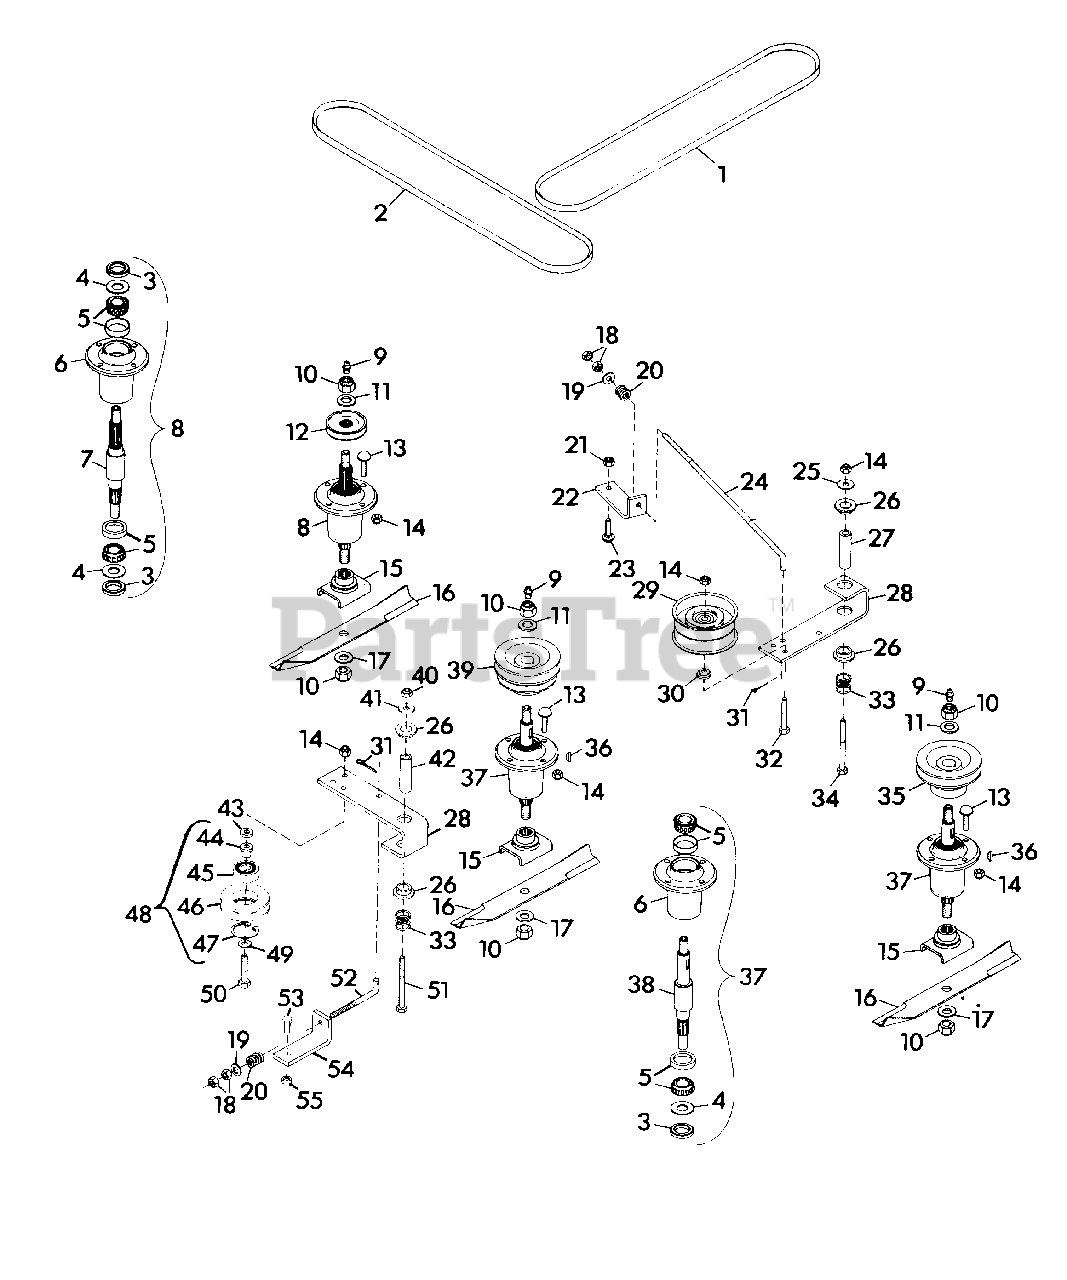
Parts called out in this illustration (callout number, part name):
1	BELT, PRO-50 MOWER
2	BELT, MOWER A44
3	SEAL, STEEL(IN 34605)
3	SEAL, STEEL(IN 21306)
4	WASHER, FLAT .975X1.970X.030(IN 34605)
4	WASHER, FLAT .975X1.970X.030(IN 21306)
5	ASSEMBLY, BEARING
6	HOUSING, BEARING
7	SHAFT, SPINDLE
8	ASSEMBLY, SPINDLE
9	FITTING, LUBE 1/8
10	NUT, LOCK 5/8-11
11	WASHER, FLAT .687X1.312X.122
12	SHEAVE, SPINDLE
13	BOLT 3/8-16X1.25 RD HD SQ NK
14	NUT, LOCK 3/8-16
15	WELDMENT, BLADE CRADLE
16	BLADE
17	WASHER, FLAT .656X1.312X.095
18	NUT, HEX 3/8-16
19	WASHER, FLAT .406X.812X.065
20	SPRING, COMP. 1X.78
21	NUT, LOCK 5/16-18
22	BRACKET, BELT TENSIONER
23	BOLT, CARRIAGE 5/16-18X1.00
24	ROD, IDLER
25	WASHER, FLAT .438X1.000X.083
26	BUSHING, NYLON .76X1X.6 FLG.
27	SPACER
28	ARM, IDLER PIVOT
29	PULLEY, IDLER
30	BUSHING
31	PIN, COTTER .09X.75
32	BOLT, HEX 3/8-16X2.25
33	SPRING, COMP. 1X.80X36 LB/N
34	BOLT, HEX 3/8-16X3.25
35	SHEAVE, SPINDLE
36	KEY, WOODRUFF .250X1 HARD
37	ASSEMBLY, SPINDLE
38	SHAFT, SPINDLE
39	SHEAVE, SPINDLE
40	NUT, LOCK 1/2-13
41	WASHER, FLAT .531X1.250X.100
42	SPACER
43	SPACER, IDLER .406X.750X.188
44	BUSHING, IDLER SHEAVE
45	BEARING, BALL
46	SHEAVE, IDLER
47	RING, RETAINING
48	ASSEMBLY, IDLER SHEAVE
49	WASHER, FLAT .375X1.125X.065
50	BOLT, HEX 3/8-16X2.00
51	BOLT, HEX 1/2-13X3.50
52	ROD, IDLER
53	BOLT, HEX 1/2-13X1.25
54	BRACKET, BELT TENSIONER
55	NUT, LOCK 1/2-13
